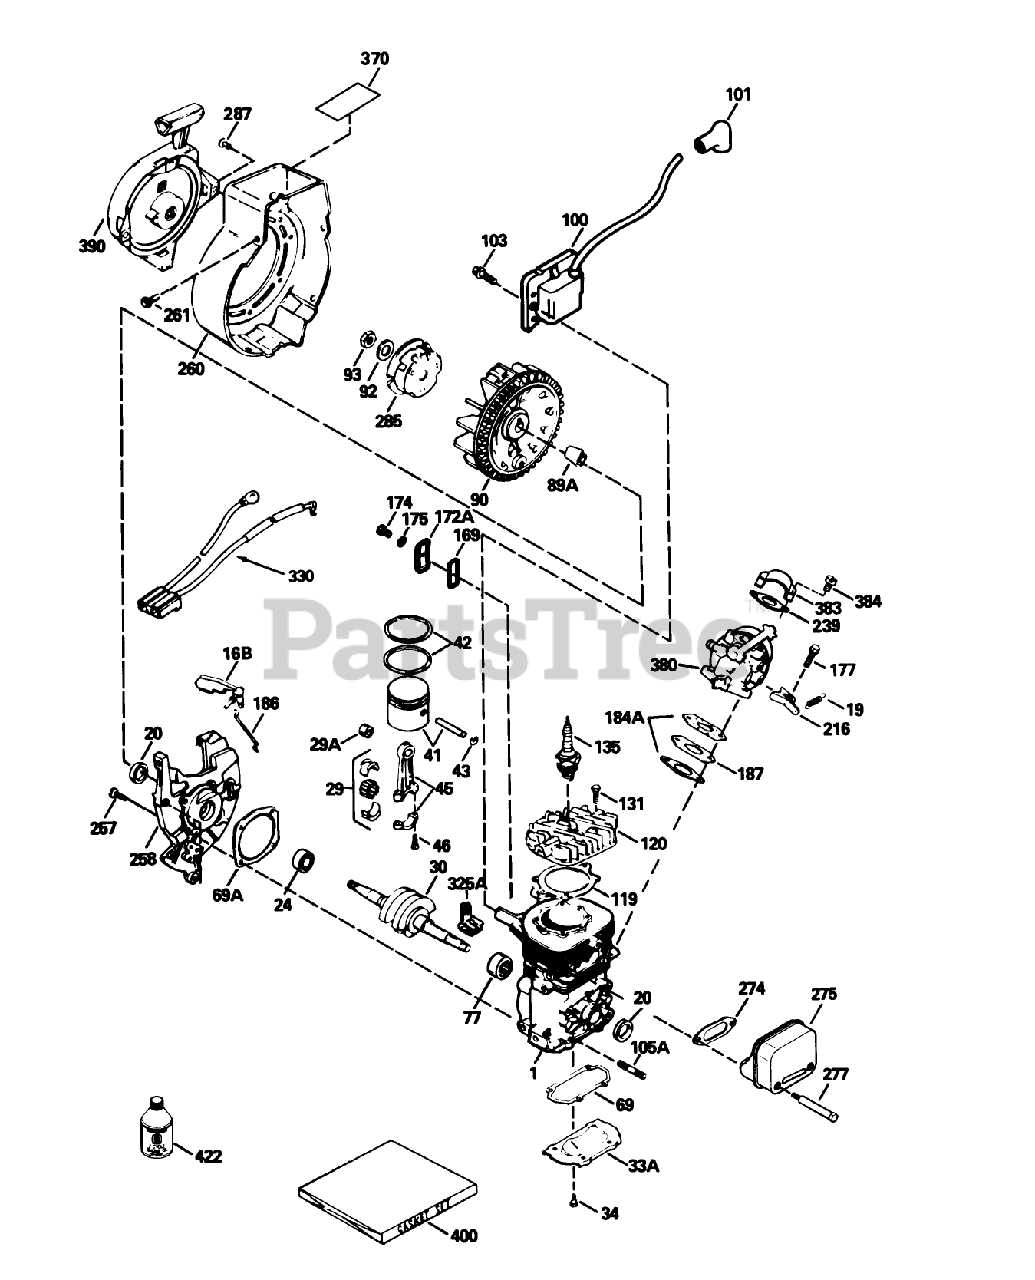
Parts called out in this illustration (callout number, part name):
1	Block Ass-y-Cylinder (Order short block if replacement is required)
16B	Vane-Air
19	Spring-Extention
20	Seal-Oil
24	Bearing-Ball
29	Needle Bearing and Liner Set (37 Needles)
29A	Bearing-Cartridge
30	Crankshaft
33A	Plate-Cover
34	Screw (T-25, 10-24 x 1/2)
41	Piston (Incl. Ref. #43)
42	Ring Set
43	Ring-Retaning
45	Rod Assy.-Connecting (Incl. Ref. #3, 3A 3B)
46	Bolt-Rod, Connecting
69	Gasket-Plate, Cover
69A	Gasket-Cover, Cylinder
77	Bearing-Cartridge
89A	Blade (20 inch)
90	Flywheel
92	Washer-Belleville
93	Nut-Flywheel
100	Solid State
101	Cover-Spark Plug
103	Screw
119	Gasket-Head, Cylinder
120	Head-Cylinder
131	Screw (T-30, 1/4-20 x 3/4)
135	Spark Plug-Resistor (R C J 8Y)
169	Cover-Compression, Release
172A	Comp. Release Cover
174	Screw (T-25, 10-24 x 1/2)
175	Washer
177	Screw (5/32 Allen, 1/4-20 x 1)
184A	Gasket-Carburetor
186	Link-Governor
187	Spacer
216	Lever-Adjusting, Rpm
239	2060A77 WIZARD ROTA
257	Screw (T-30, 1/4-20 x 5/8)
258	Base Assy.-Blower Housing (Incl. Ref. #10)
260	Housing-Blower
261	Screw (1/4-20 x 1/2)
274	Gasket-Exhaust
275	Muffler (Incl. Ref. #274 277)
277	Screw (1/4-20 x 2-3/4)
285	Cup-Starter
287	Rivet-Pop
325A	Clip-Wire
330	Harness-Wire
370	Decal-Warning
380	Carburetor (Incl. Ref. #184A)
383	Baffle-Carburetor
384	Screw
390	Starter-Rewind
400	Gasket Set
422	2-Cycle Oil (8oz)
